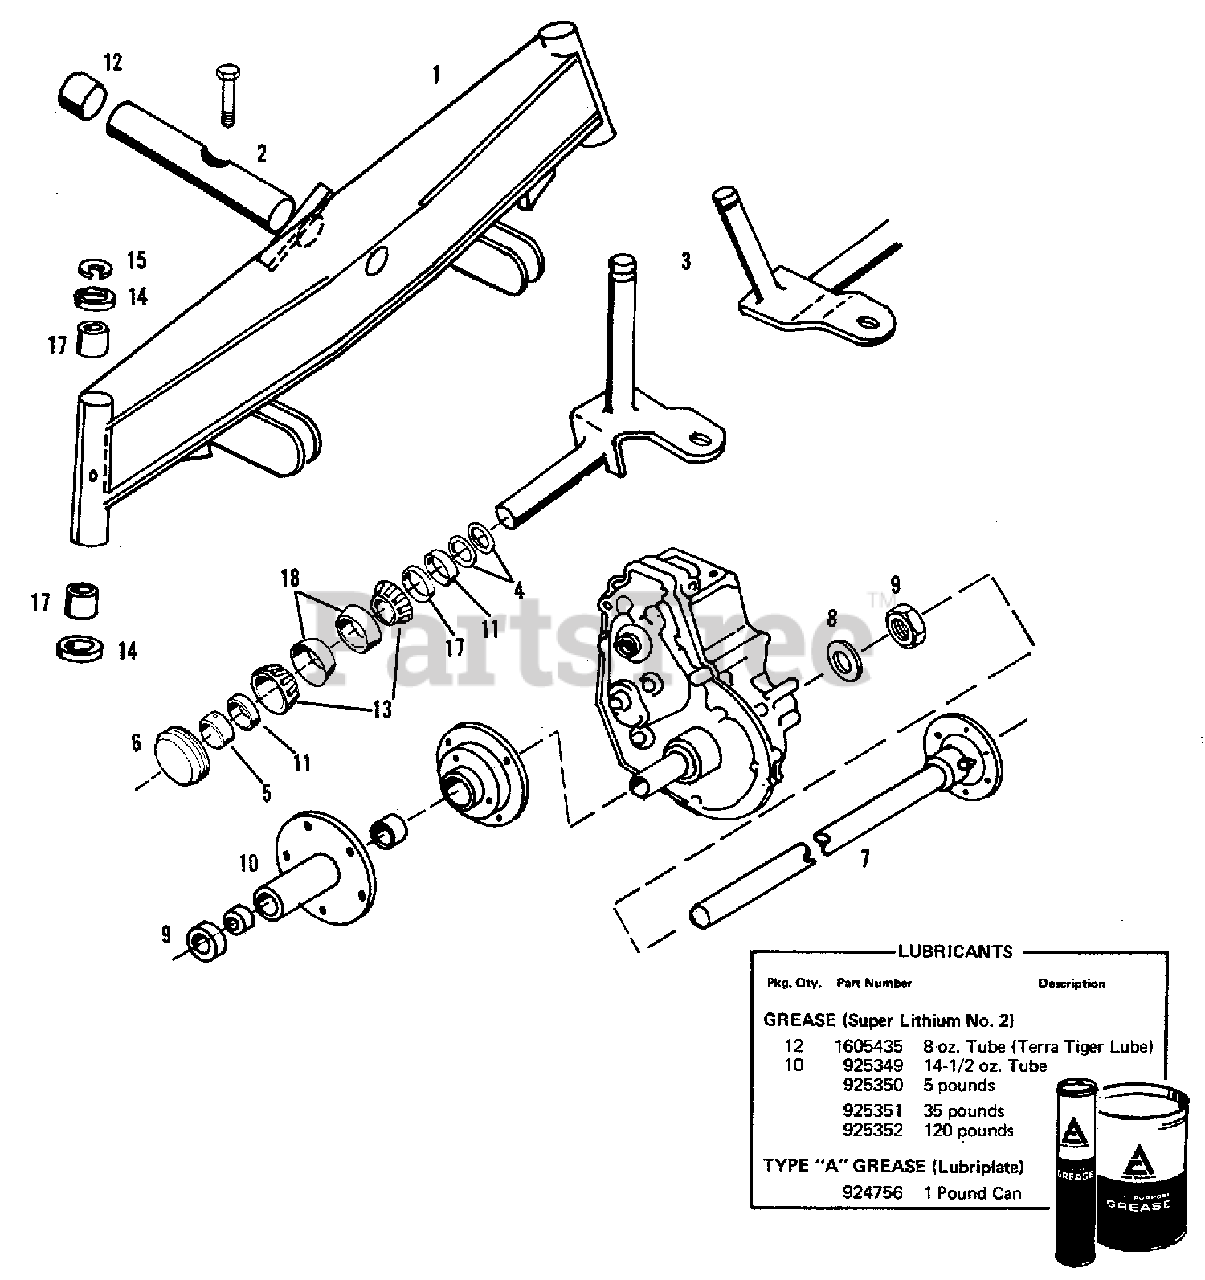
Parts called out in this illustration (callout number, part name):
1	AXLE ASSEMBLY, Front (Includes BUSHINGS)
2	SHAFT, Axle Pivot
2	CAPSCREW, 1/2NC x 2-1/4, Gr8
2	LOCKWASHER, 1/2
2	NUT, 1/2NC
3	SPINDLE ASSEMBLY, L.H.
3	SPINDLE ASSEMBLY, R.H.
5	COLLAR, Set
5	SETSCREW, 5/16NC x 5/16
7	AXLE ASSEMBLY, Rear
9	COLLAR, Set
9	SETSCREW, 5/16NC x 3/8, Gr8
10	HUB ASSEMBLY, R.H. Wheel (Includes BUSHINGS & 1 FITTING)
10	BUSHING, Hub
10	FITTING, 1/4-28 x 90 Degrees (Package of 10)
10	EASY-OUT, 1/4 Inch (Service Only)
12	BEARING, Sleeve (In Main Frame Assembly)
13	BEARING, Cronical Roller
14	WASHER, .766 x 1-3/8 x 12 Ga.
15	RING, Retaining
17	BUSHINGS, Axle
18	BEARING, Cup
